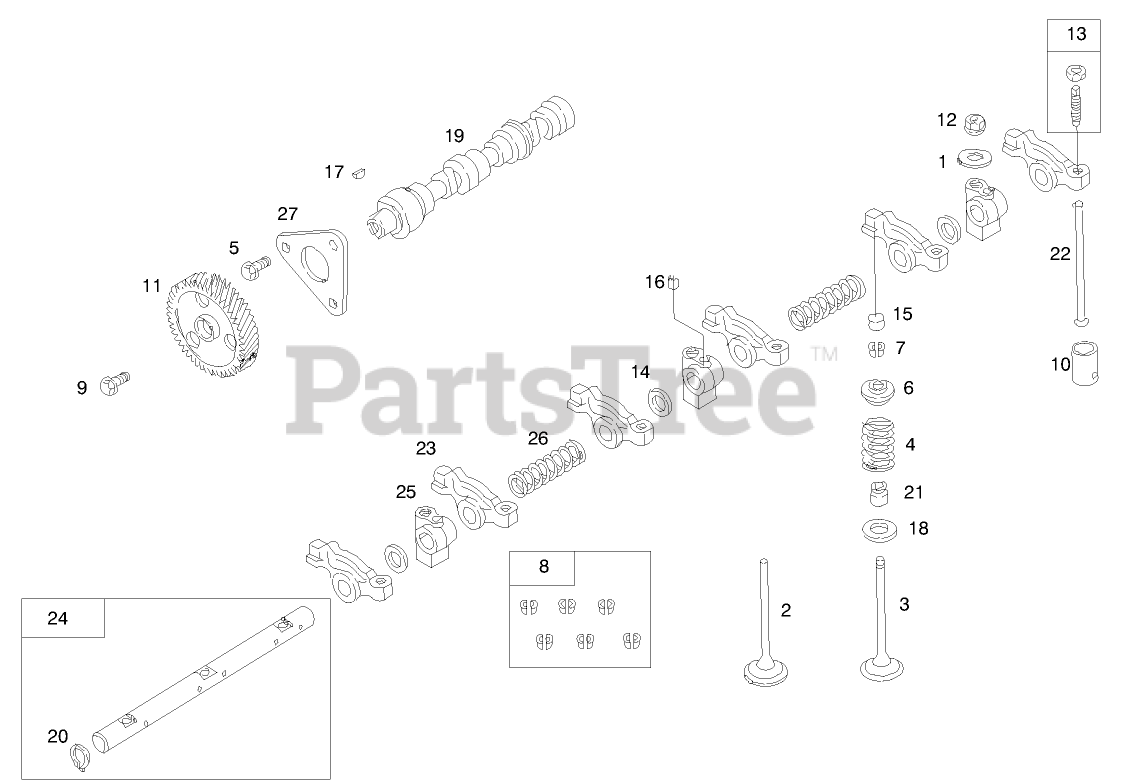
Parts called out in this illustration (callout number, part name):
1	WASHER-FLAT
2	VALVE-EXHAUST
3	VALVE-INTAKE
4	SPRING-VALVE
5	SCREW-HEX
6	RETAINER-VALVE
7	KEEPER-VALVE (SET)
9	SCREW-METRIC
10	TAPPET-VALVE
11	GEAR-CAM
12	NUT-HEX, METRIC
13	ADJUSTER-ARM, ROCKER
14	WASHER-SPACER
15	CAP-VALVE
16	SCREW-METRIC
17	KEY-TIMING
18	SEAT-SPRING, VALVE
19	SHAFT-CAM
20	RETAINER
21	SEAL-VALVE
22	ROD-PUSH
23	ARM-ROCKER
24	SHAFT-ARM, ROCKER
25	SUPPORT-ARM, ROCKER
26	SPRING-SHAFT, ROCKER
27	RETAINER-CAMSHAFT
